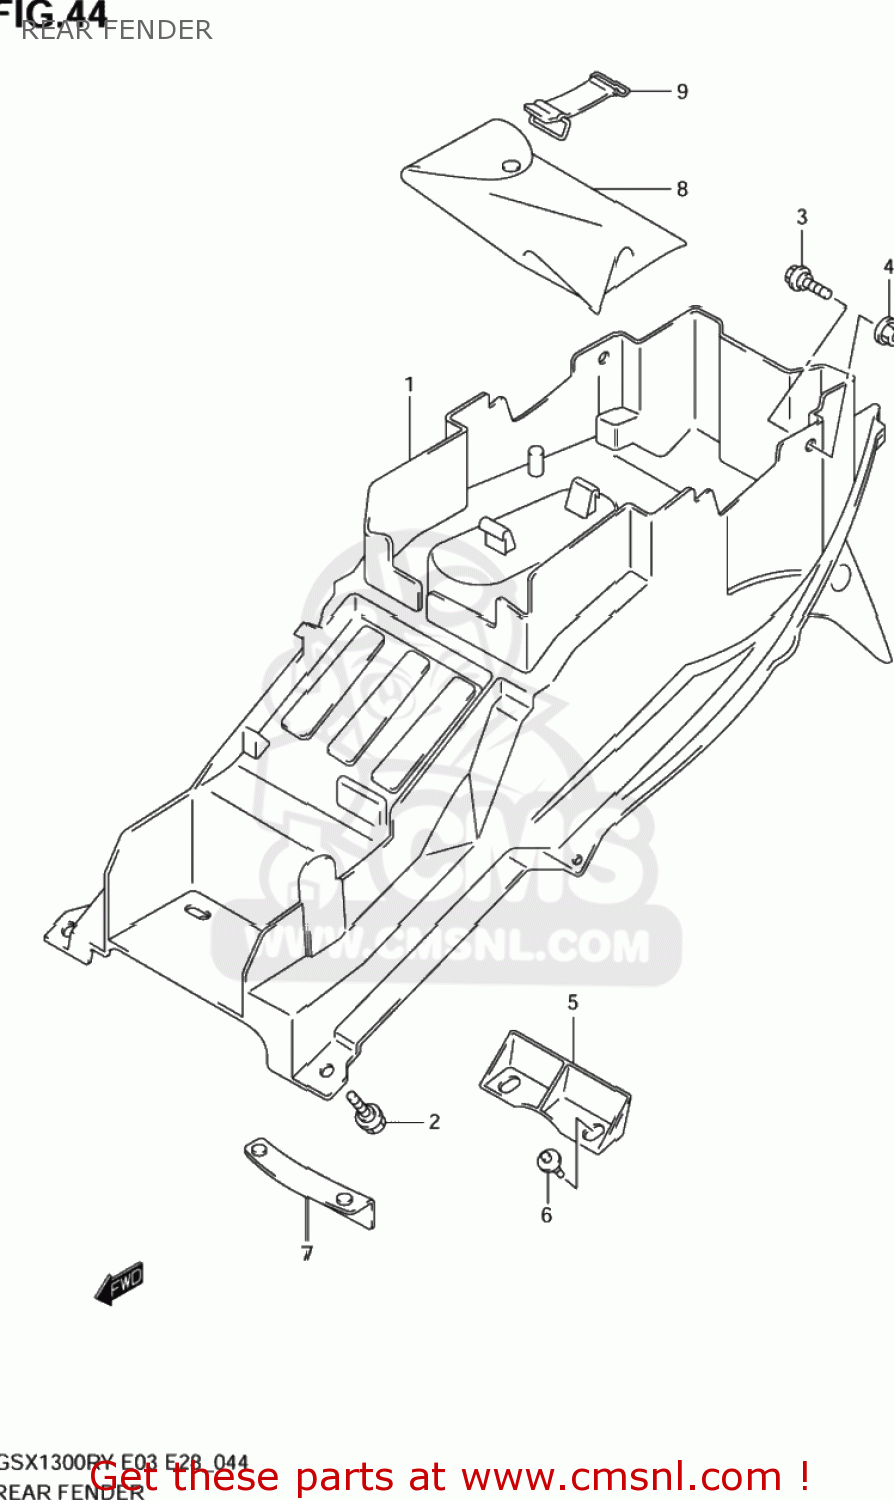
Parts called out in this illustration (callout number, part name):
1	FENDER,RR
2	BOLT(6X16)
3	BOLT(6X16)
4	NUT
5	MUDGUARD,RR FENDER
6	CLIP
7	MUDGUARD,RR FENDER FR UPR
8	TOOL ASSY
9	BAND
